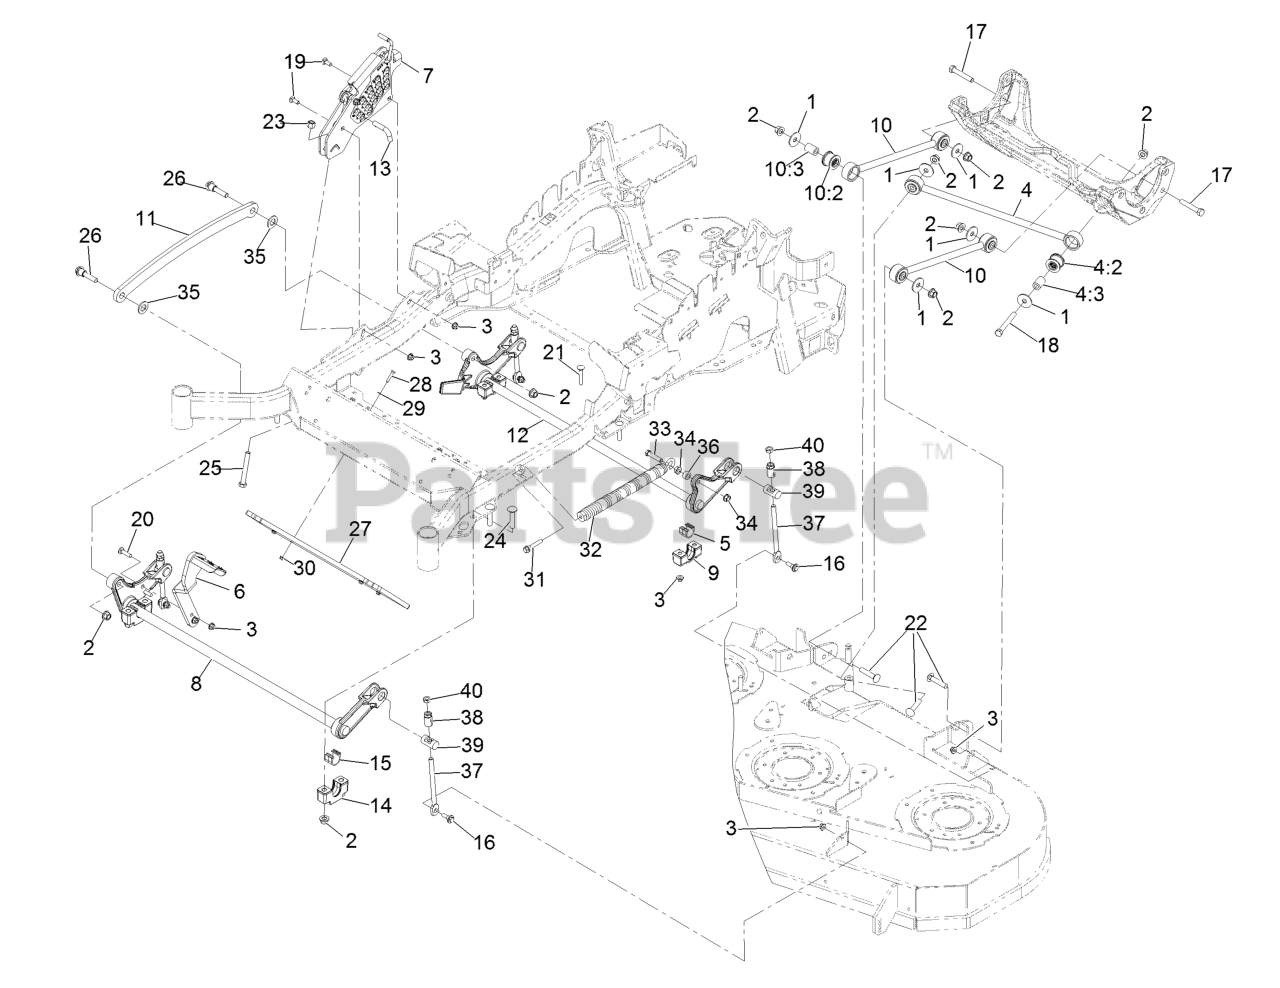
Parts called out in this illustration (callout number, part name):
2	Nut-Lock 1/2-13
3	Nut-Nyloc 3/8-16 Flg
4	Panhard Rod ASM
4:2	Bushing-Suspension, Rubber
5	Bearing-Cross Shaft, Rear
6	Lever-Foot
7	HOC ASM
8	Decklift-Front
9	Support-Cross Shaft, Bearing Rear
10	Deck Strut ASM
10:2	Bushing-Suspension, Rubber
11	Link-Lift, Deck
12	Lift-Deck, Rear
13	Pin-HOC
14	Support-Cross Shaft, Bearing
15	Bearing-Cross Shaft, Front
16	Screw-Hex Flange 3/8-16 X .80
17	Screw-HH 1/2-13 X 3
18	Screw-HH 1/2-13 X 4
19	Bolt-Carriage 3/8-16 X 1
20	Bolt-Carriage 3/8-16 X 1 1/2
21	Bolt-Carriage 3/8-16 X 2 1/4
22	Bolt-Carriage 1/2-13 X 2 1/2
23	Nut-Nyloc 1/2-13
24	Bolt-Carriage 1/2-13 X 2 1/2 Spl Neck
25	Bolt-HH 1/2-13 X 4 Tap
26	Screw-Hex Flange 1/2-13 X 1.90
27	Weight-Toe Board
28	Screw-HH 1/4-20 X 1 1/4
29	Washer-1/4 SAE
30	Nut-Nyloc 1/4-20 Flg
31	Screw-Shcs 3/8-16 X 2.212
32	Spring-Extension
33	Screw-HH 7/16-14 X 2
34	Nut-Whizlock 7/16-14
35	Washer-3/4 SAE
37	Link-Adjuster, Deck Lift
38	Adjuster-Lift, Deck
39	Trunnion
40	Nut-Jam 1/2-13
